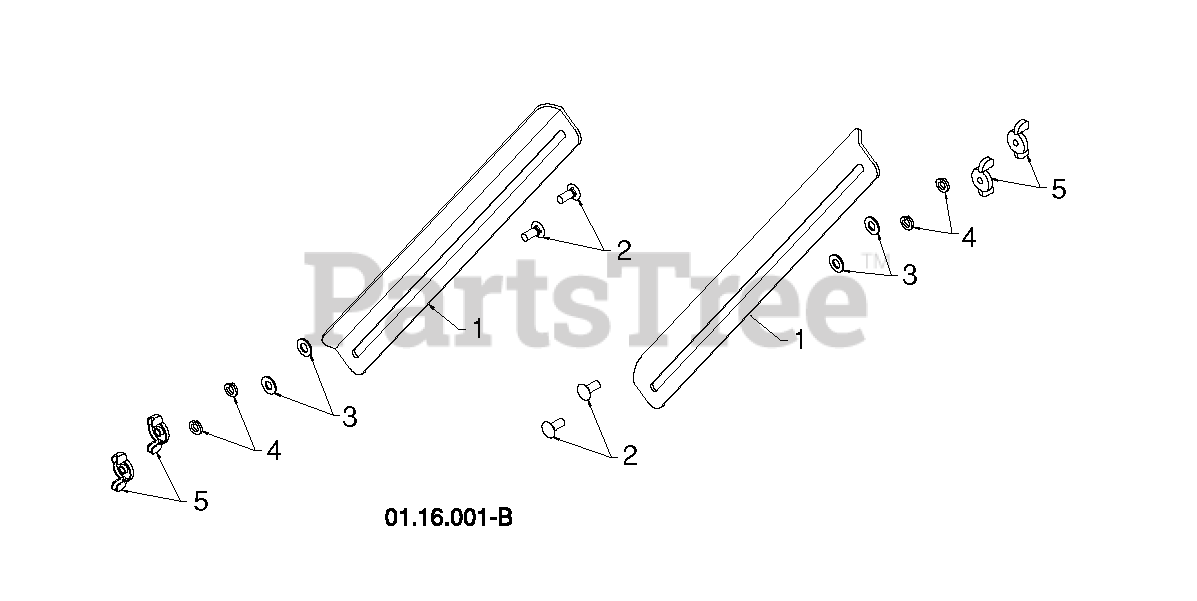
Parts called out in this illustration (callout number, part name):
1	DRIFT CUTTER BAR
2	BOLT
3	WASHER, NYLON FRICTION
4	LOCKWASHER
5	NUT WING PM
